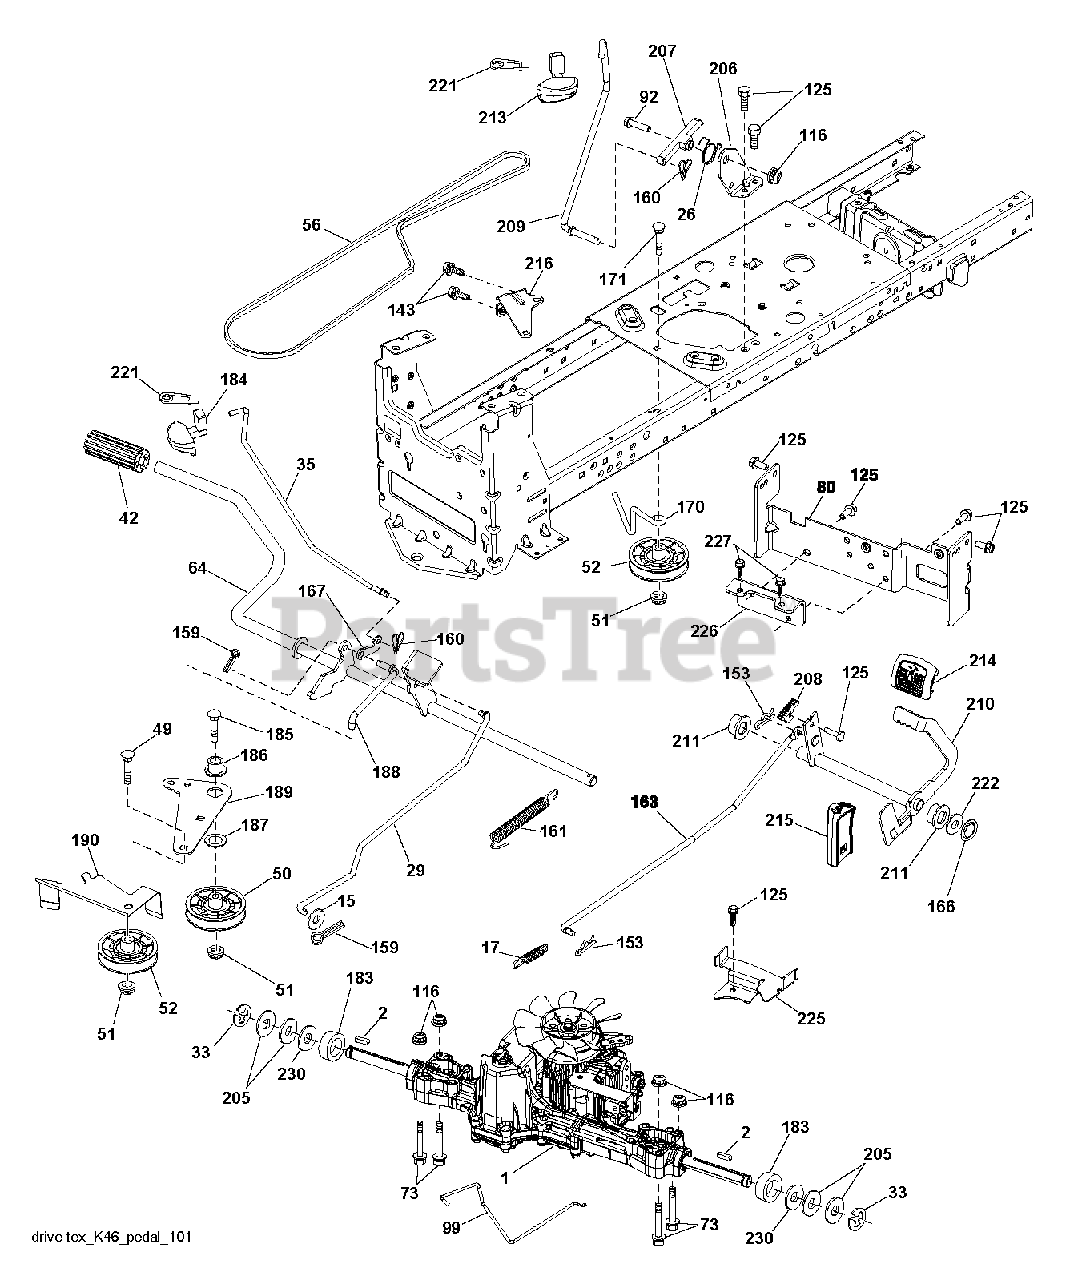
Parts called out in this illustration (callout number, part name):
2	SQUARE KEY
15	WASHER
17	SPRING.BRAKE.K46.GREEN
26	SPRING.RETURN.CRUISE
29	ROD.BRAKE.K46
35	ROD.BRAKE.PARTK.HUSQ.TEX
42	PEDAL COVER T
50	IDLER.FLAT.910.OFFSET
51	NUT LOCK FLG 3/8-16 UNC
52	IDLER.V-GROOVE.910.OFFSET
56	V-BELT.MOWER.92.40.42/K46
64	SHAFT.ASM.PEDAL.BRK.CNTR
80	STRAP.TORQUE.K46.K57R.TT
92	BOLT
99	ROD.SPRING.BYPASS.K46.LT.Z
116	NUT LOCK HEX FLANGE 5/16-18
125	SCREW
143	SCREW LT
153	RETAINER M
159	COTTER PIN
160	RETAINER CLIP
161	SPRING, RETURN LT
163	ROD.CONTROL.PEDAL.K46
166	NUT.PUSH.625
167	LATCH.BRAKE.SPRING
170	KEEPER.V-IDLER.CENTER.
183	SPACER AXLE
184	RB HANDLE.PARKG.BRK.HUS/PRED
186	SPACER.RETAINER
187	WASHER 12/32X2X10GA
188	RP LINK.CLUTCH.GROUND.DRIVE
189	BELLCRANK.GROUND.DRIVE.TEX.
190	KEEPER.BELLCRANK.DRIVE
206	BRKT.MOUNT.LATCH.CRUIS
207	LATCH.CONTROL.CRUISE
208	GEAR.SECTOR.CONTROL.CR
209	ROD.CONTROL.CRUISE.GT.
210	ROCKER.ASM.PEDAL.CONTR
211	BEARING.NYLON
213	KNOB.CONTROL.CRUSIE.HU
214	PEDAL.FORWARD.PAD.TEX
215	PEDAL.REVERSE.TEX.GT.4
216	BRACKET.PULLEY.IDLER.W/TEX
221	RETAINER.SPRING.CLIP.H
222	WASHER 21/32 X 1-1/4 X 10 GA.
225	KEEPER.BELT.TRANSAXLE.K46
226	BRACKET.MOUNT.TORQUE.K46.TLT
227	SCREW
230	WASHER.HARDENED
